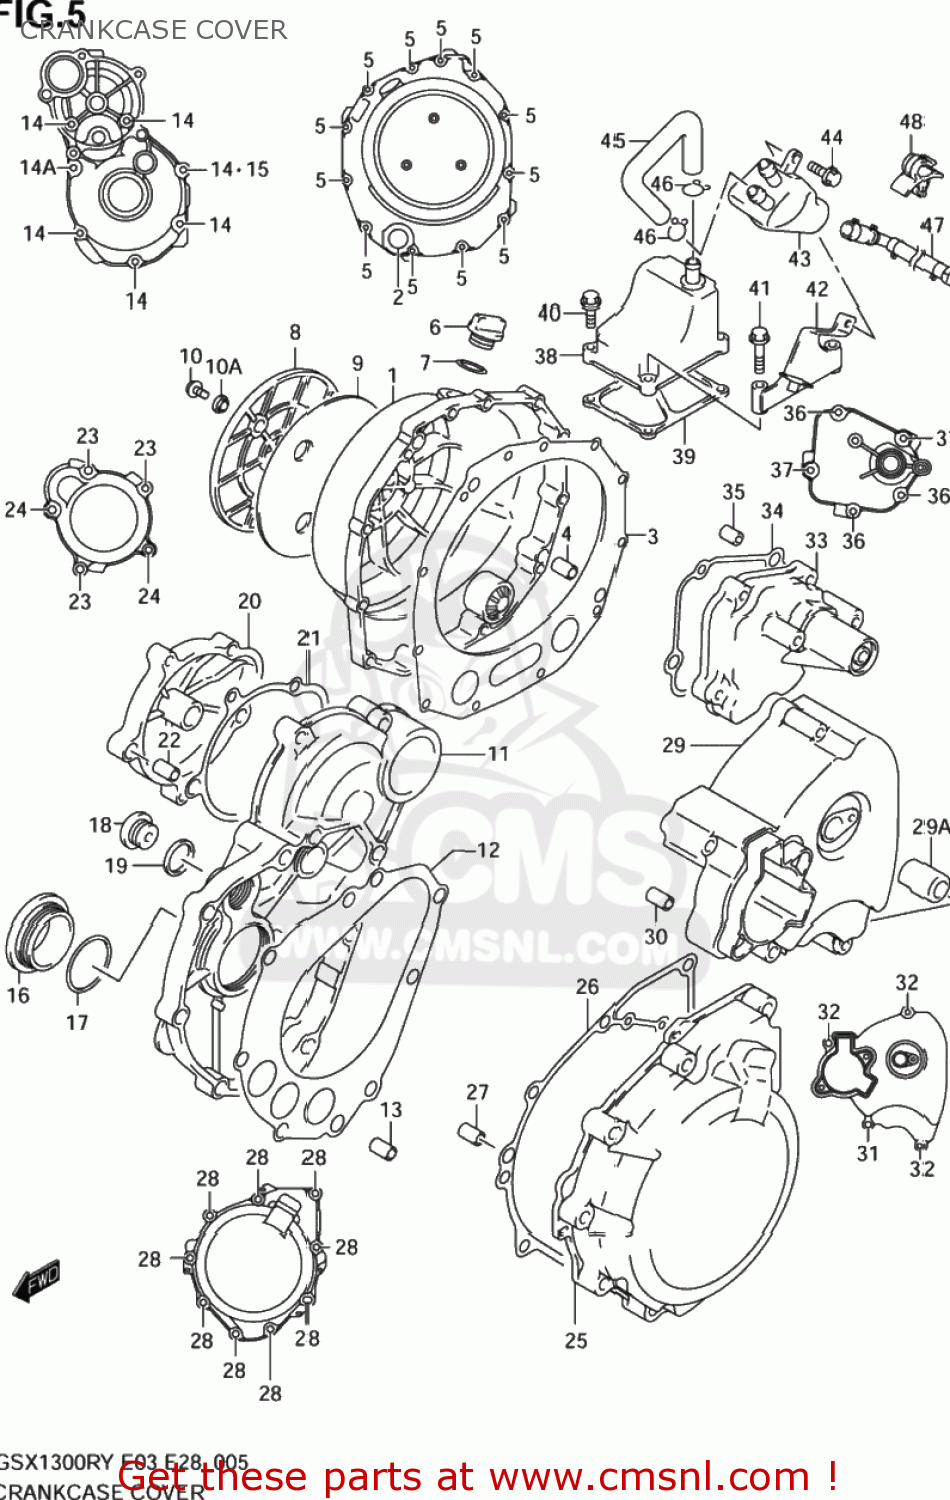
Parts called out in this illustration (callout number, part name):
1	COVER,CLUTCH
2	LENS,OIL LEVEL CHECK
3	GASKET,CL COVER (NAS)
4	PIN
5	BOLT
6	PLUG
7	O RING(D:3.1,ID:16.8)
8	COVER,CLUTCH OUTER
9	CUSHION,CLUTCH OUTER COVER
10	SCREW(6X16)
10A	WASHER,CLUTCH OUTER COV SCREW
11	COVER,STARTER CLUTCH
12	GASKET,STARTER CLUTCH COVER (NAS)
13	PIN
14	BOLT
14A	BOLT
15	GASKET(5.8X13X1.2) (NAS)
16	PLUG
17	O RING(D:3.1,ID:32.7)
18	PLUG,16X8
19	GASKET(16X22X2) (NAS)
20	CAP,STARTER IDLE GEAR
21	GASKET,START IDLE GEAR CAP (NAS)
22	PIN
23	BOLT
24	BOLT
25	COVER,MAGNETO
26	GASKET,MAGNETO COVER (NAS)
27	PIN
28	BOLT
29	COVER,ENGINE SPROCKET
29A	PROTECTOR,ENGINE SPRKT COVER
30	PIN
31	BOLT
32	BOLT
33	COVER,GEAR SHIFT
34	GASKET,GEAR SHIFT COVER (NAS)
35	PIN
36	SCREW
37	BOLT
38	COVER,BREATHER
38A	UNION
39	GASKET,BREATHER COVER (NAS)
40	BOLT,G/S SWITC
41	BOLT
42	BRACKET,OIL RETURN TANK
43	TANK,OIL RETURN
44	BOLT
45	HOSE,BREATHER
46	CLIP
47	HOSE,OIL DRAIN
48	CLAMP
